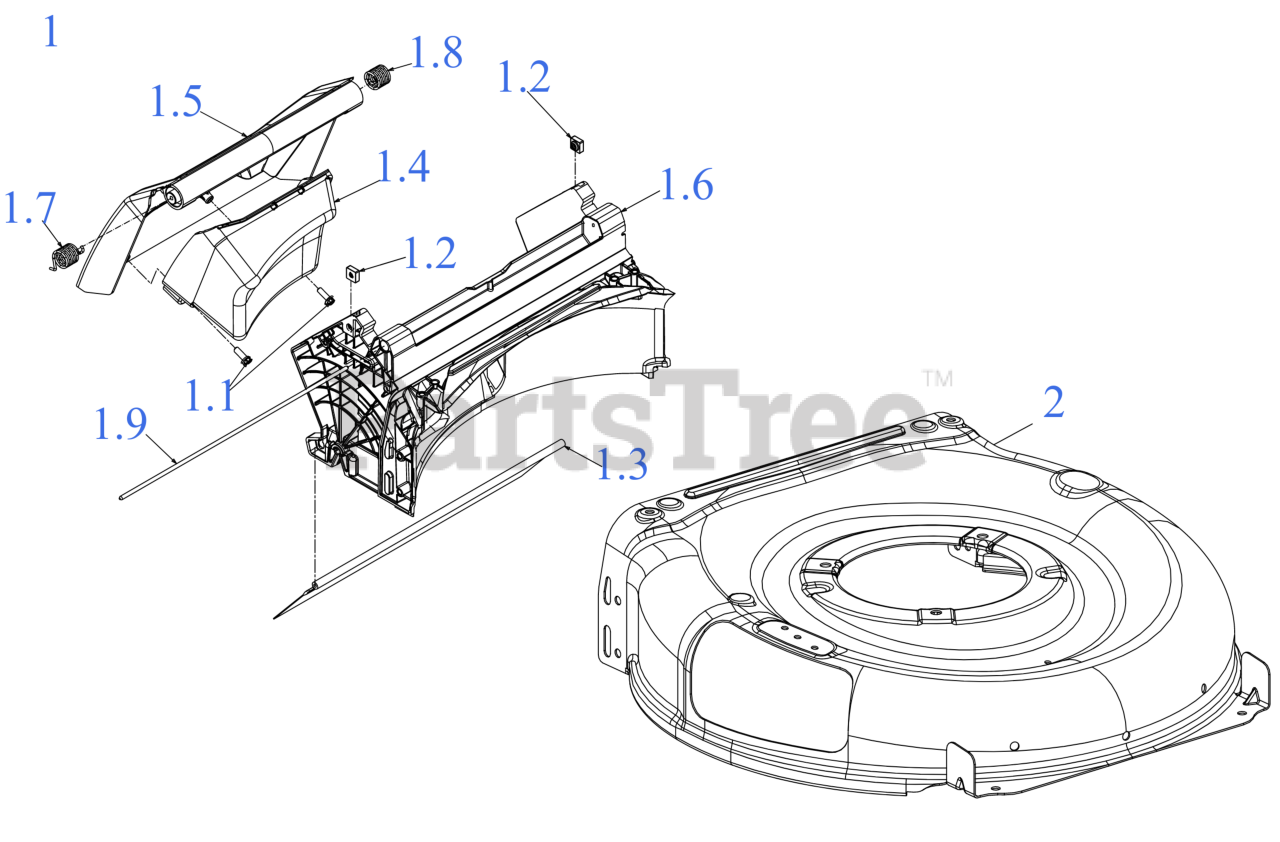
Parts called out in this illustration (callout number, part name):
1	REAR BAG BAFFLE
1.1	SCREW 1/4 x .750
1.2	SQUARE LOCK NUT 1/4X20
1.3	TRAILSHIELD
1.4	Not Serviceable/ Order Complete Assembly
1.5	Not Serviceable/ Order Complete Assembly
1.6	Not Serviceable/ Order Complete Assembly
1.7	TORSION SPRING (RH)
1.8	TORSION SPRING (LH)
1.9	Not Serviceable/ Order Complete Assembly
